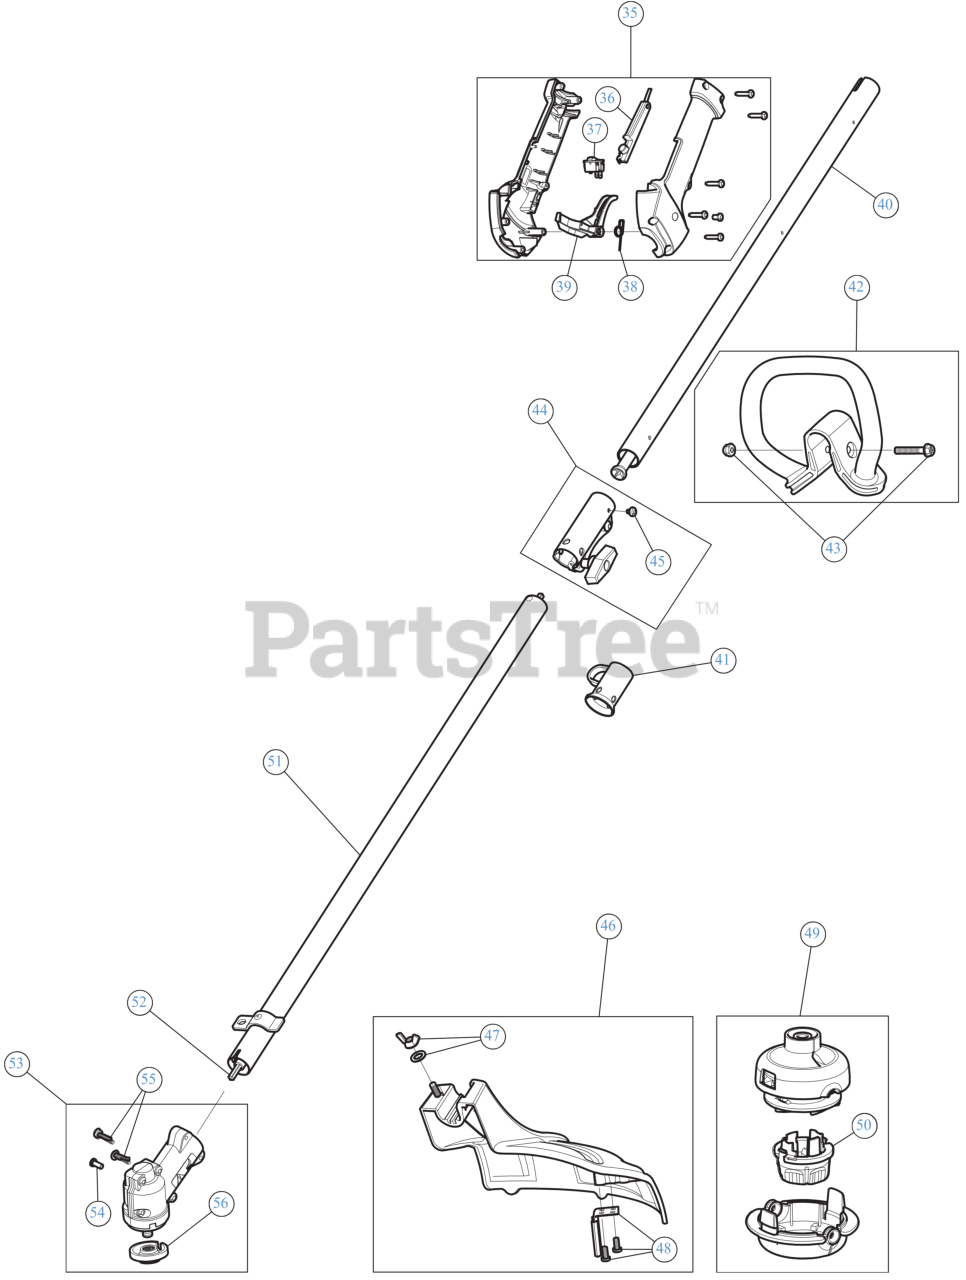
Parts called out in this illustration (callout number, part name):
35	THROTTLE GRIP ASSEMBLY
36	LEVER LOCK OUT
37	SW, MOMENTARY ON/O
38	SPRING TRIG
39	THROTTLE TRIGGER
40	BOOM ASSEMBLY UPR
41	HANGER
42	D-HANDLE
43	BOLT 1/4-20X1 1/2
44	COUPLER ASSEMBLY
45	SCREW, 10-32X.250 TA
46	GUARD/BLADE ASM
47	BLADE GUARD MOUNTING HARDWARE
48	BLADE ASSEMBLY W/HDW
49	HEAD ASSEMBLY
50	BUMP KNOB (LIBERTY RED)
51	BOOM ASSEMBLY LOWER
52	LOWER DRIVE SHAFT
53	GEARBOX LCBC
54	SCREW, 8-32 x .312 P
55	SCREW #
56	CUTTING HEAD SPACER
